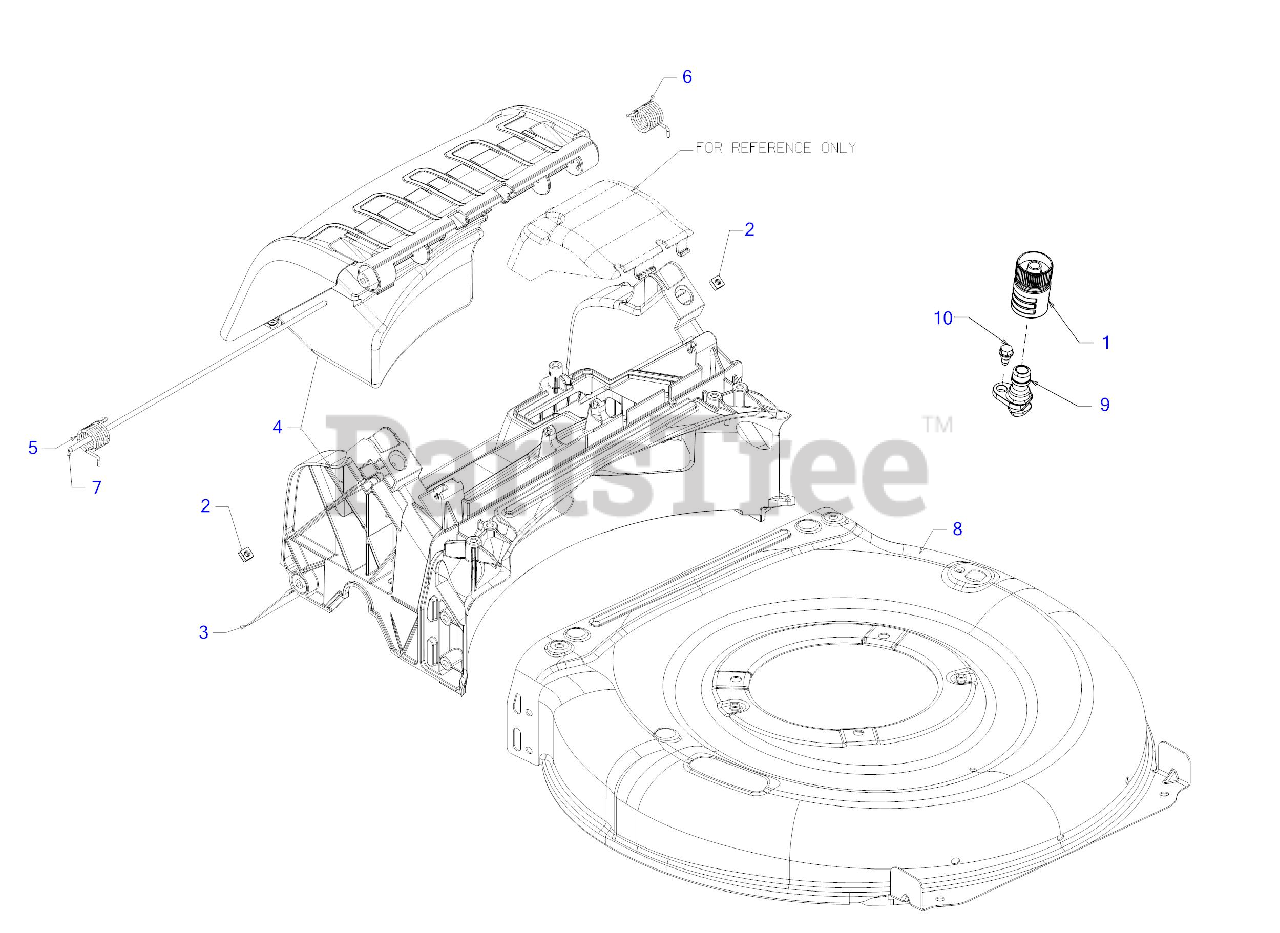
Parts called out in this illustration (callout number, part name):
1	WATER NOZZLE
2	SQUARE NUT 1/4-20
3	TRAILSHIELD
4	REAR BAG BAFFLE ASSEMBLY
5	TORSION SPRING (RH)
6	TORSION SPRING (LH)
7	REAR DOOR PIVOT ROD
9	DECK WASH NOZZLE
10	SHOULDER SCREW 1/4-20 x .50
